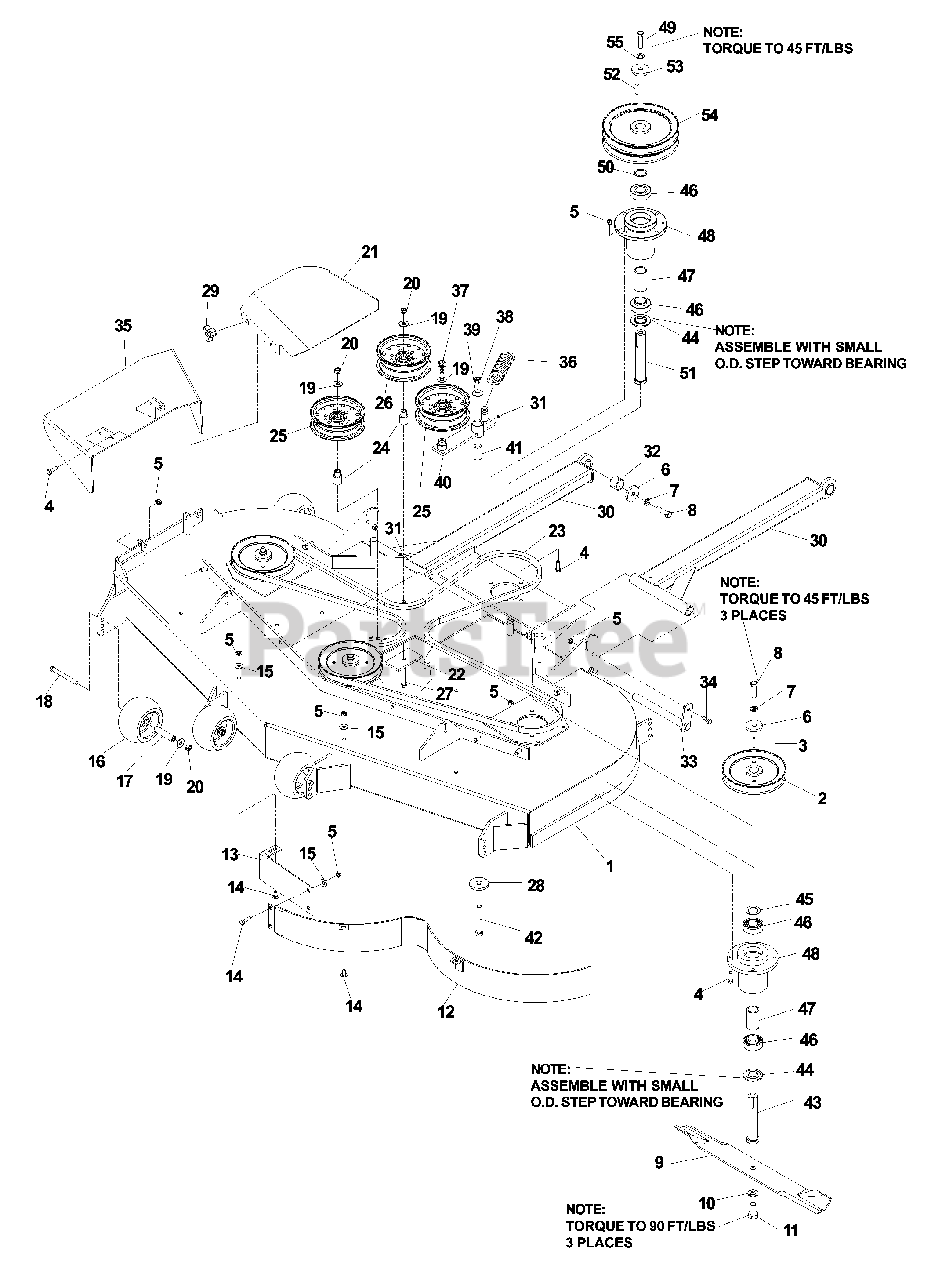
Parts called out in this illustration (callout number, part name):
1	61" Deck w/decals
3	Key, 1/4" sq. x 1 1/8
4	Bolt, 5/16-18 x 1
5	Nut, 5/16-18, centerlock
6	Washer, heavy
7	Lockwasher, 7/16
8	Bolt, 7/16-20 x 1 1/2
9	Blade, 21"
10	Lockwasher, 5/8
11	Bolt, 5/8-18 x 1 1/4
12	Main weldment
13	Baffle, center
14	Bolt, 5/16-18 x 5/8, carriage
15	Washer, 5/16
16	Anit-scalp roller
18	Bolt, 3/8-16 x 3 1/2
19	Washer, 3/8
20	Nut 3/8-16, centerlock
21	Belt shield, 61", right
22	Pad
24	Bushing, idler
25	Pulley, idler
26	Pulley, idler, tall
27	Bolt, 3/8-16 x 2 1/2
28	Washer, support
29	Knob, three prong
30	Strut weldment
31	Zerk
32	Spacer, strut
33	Pin weldment
34	Bolt, 5/16-18 x 3/4
35	Chute, discarge
37	Bolt, 3/8-16 x 1, ser.
38	Nut, 1/2-13, nyloc
39	Washer, 1/2
41	Bushing, pivot
42	Bolt, 1/2-13 x 3 1/4, GD. 5
44	Spacer, combo
45	Bushing, mach. 18 ga
46	Bearing
49	Bolt, 7/16-20 x 1 1/2
50	Bushing, mach., 18ga
52	Key, 1/4" sq. x 1 1/8"
53	Washer, heavy
55	Lockwasher, 7/16
